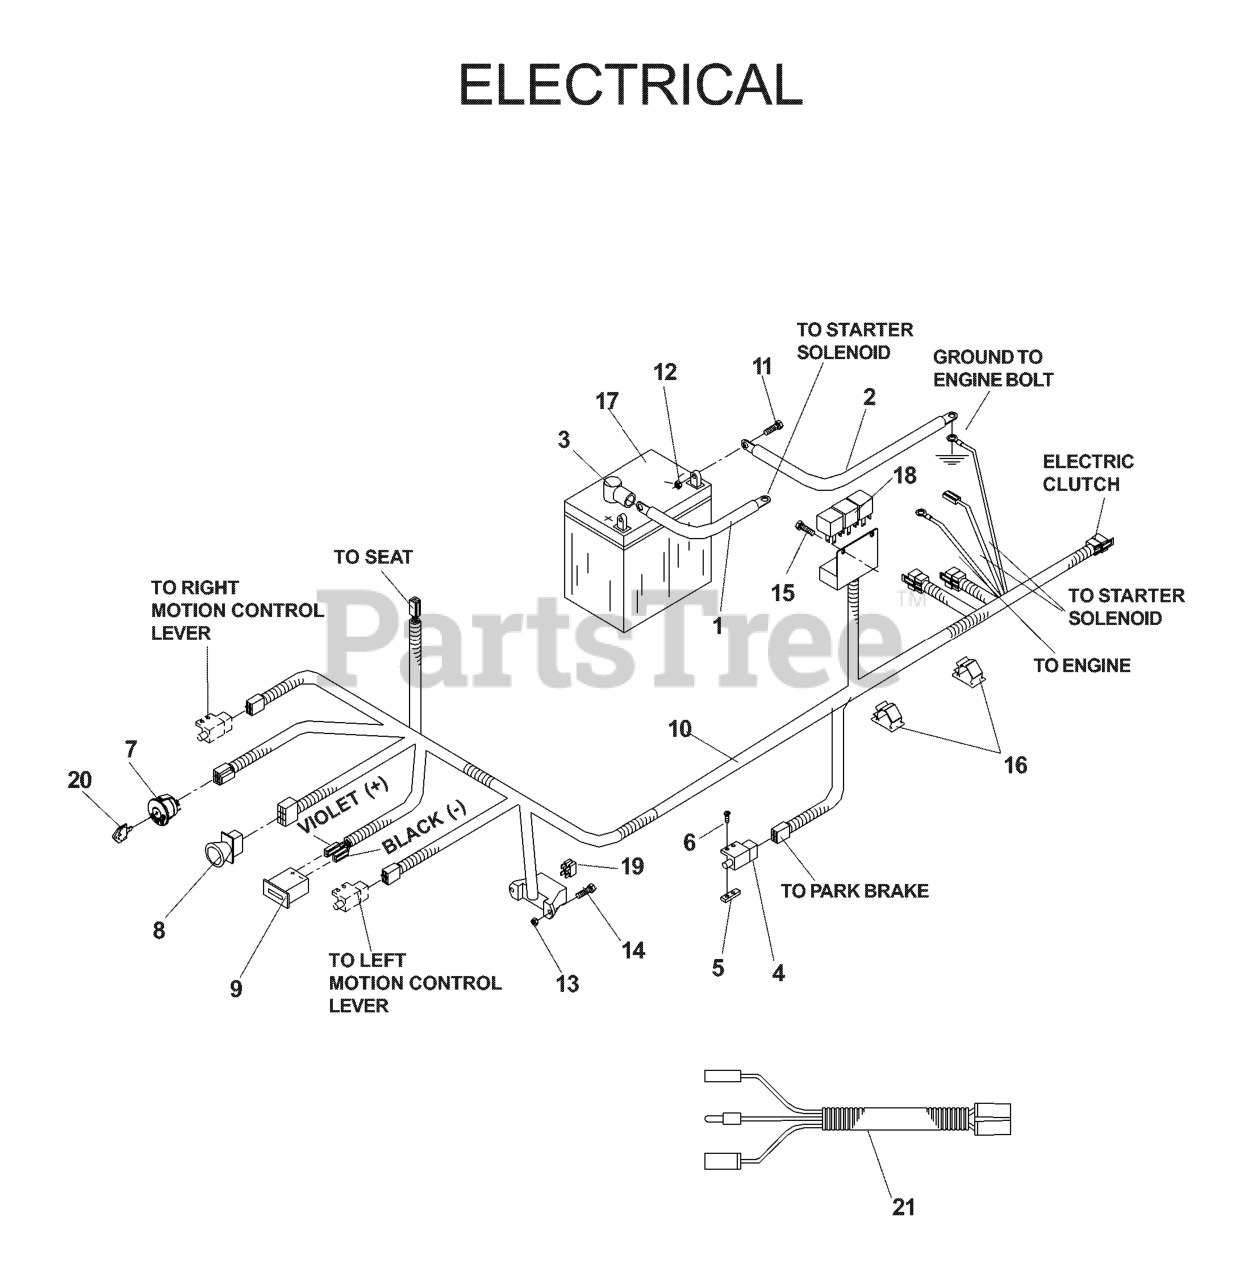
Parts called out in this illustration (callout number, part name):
1	CABLE POSITIVE, LONG
2	CABLE-NEGATIVE
4	SWITCH, INTERLOCK
5	TAPPED PLATE
6	SCREW #10-24 X 5/8
7	RP IGNITION SWITCH
8	RP.SWITCH, BLADE
9	HOUR METER
10	FRAME HARNESS
11	HCS 5/16C X 3/4
12	NUT 5/16 NYLOC
13	NUT 10-24 NYLOC
14	SCREW, #1--24 X 1/2 SLOTTED
15	SCREW #10 X 1/2 SELF TAPPING
16	PUSH-MOUNT WIRE CLIP
17	BATTERY, 12 V 330 AMP
19	FUSE, 7.5 AMP 32 VOLT ATO
20	KEY
21	KAW PIGTAIL
